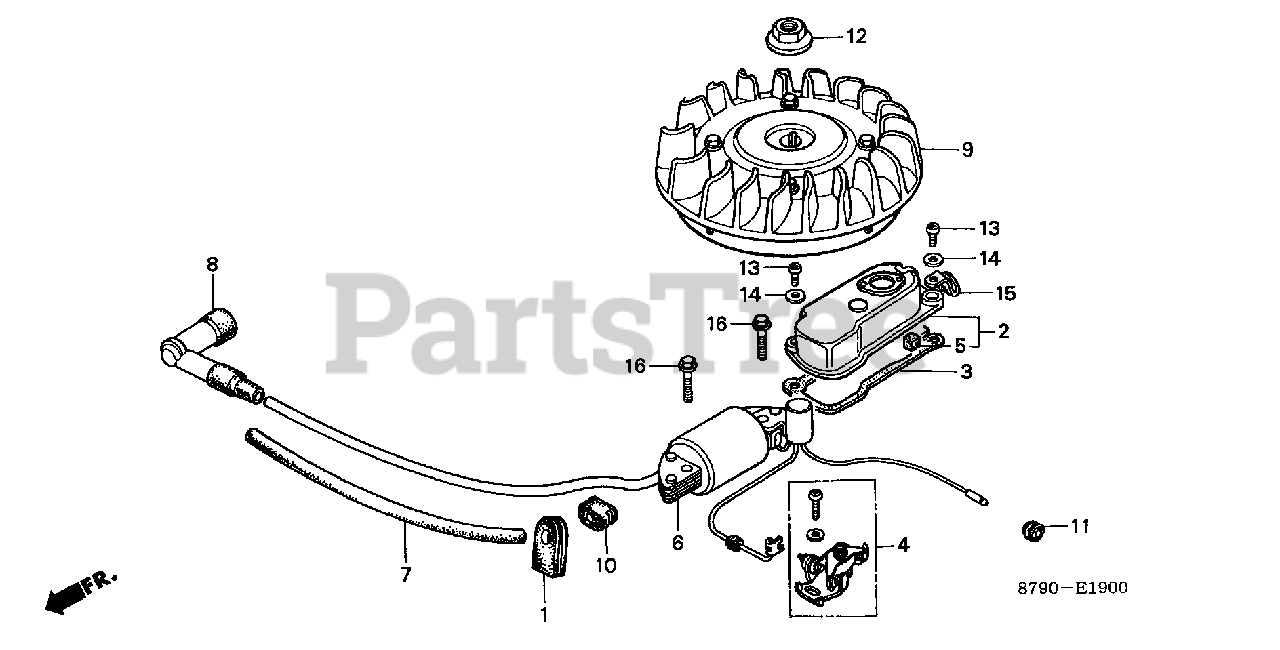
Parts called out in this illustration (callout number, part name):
1	GROMMET, CORD
2	COVER ASSY., BREAKER (NOT AVAILABLE)
2	COVER, BREAKER
3	GASKET, BREAKER COVER (NOT AVAILABLE)
4	POINTS ASSY.
6	COIL ASSY., IGNITION (DENSO)
7	TUBE, IGNITION RUBBER
8	CAP ASSY., NOISE SUPPRESSOR
8	CAP ASSY., NOISE SUPPRESSOR (NICHIRIN)
9	FLYWHEEL ASSY. (DENSO)
10	GROMMET, WIRE
11	GROMMET, RR. TURN SIGNAL WIRE (NOT AVAILABLE)
12	NUT, SPECIAL (14MM)
13	SCREW, PAN (4X8)
14	WASHER, PLAIN (4MM)
15	CLIP, WIRE (2X40)
16	BOLT, FLANGE (6X25) (NOT AVAILABLE)
